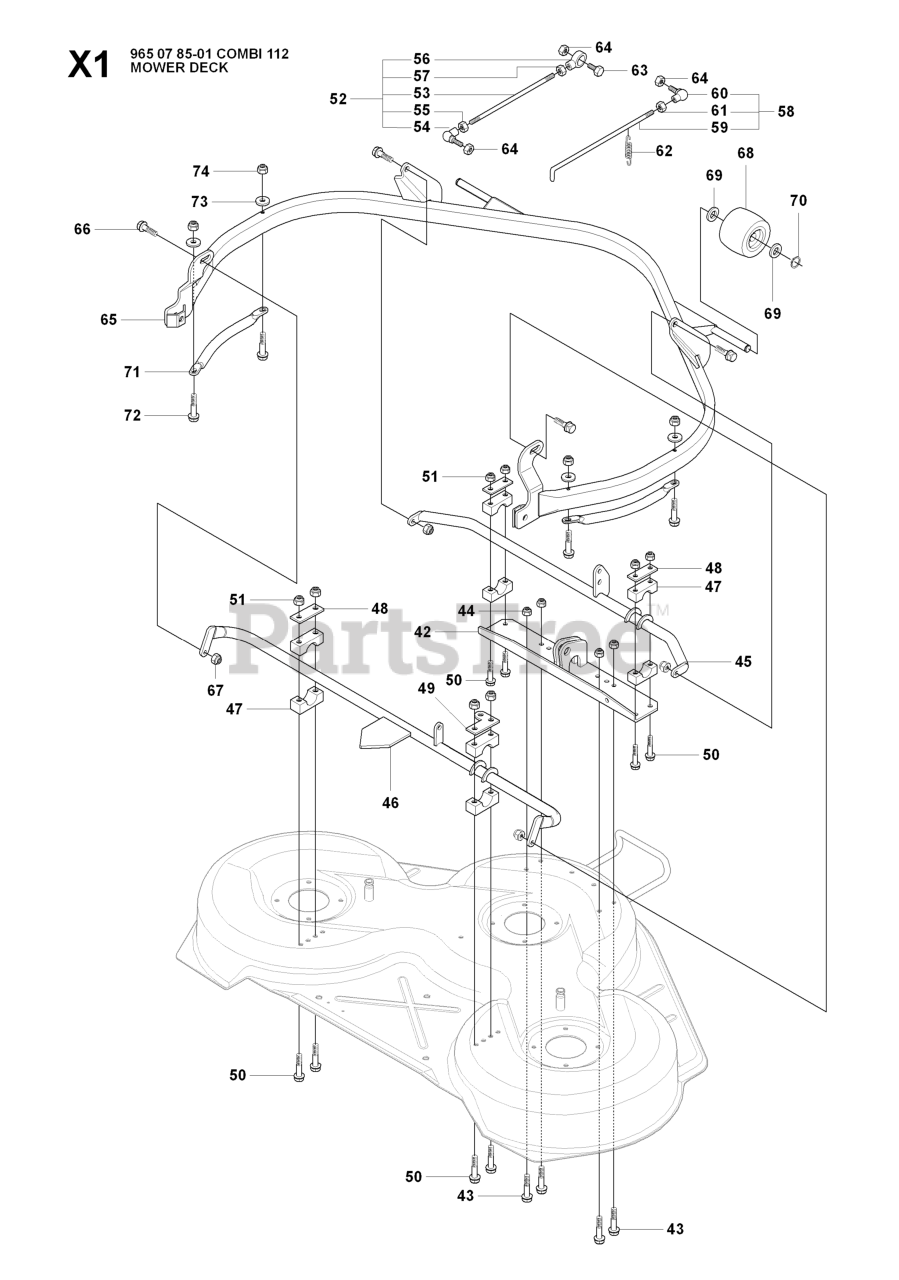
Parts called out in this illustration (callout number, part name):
44	LOCKNUT M8
51	LOCKNUT M8
52	PARALLEL RODY ASSY
57	NUT
58	CLUTCH ROD ASSY
64	NUT
67	LOCKNUT M8
68	DECK ROLLER, FRONT
70	RETAINING RING SGA 15
73	WASHER
74	LOCKNUT M6
